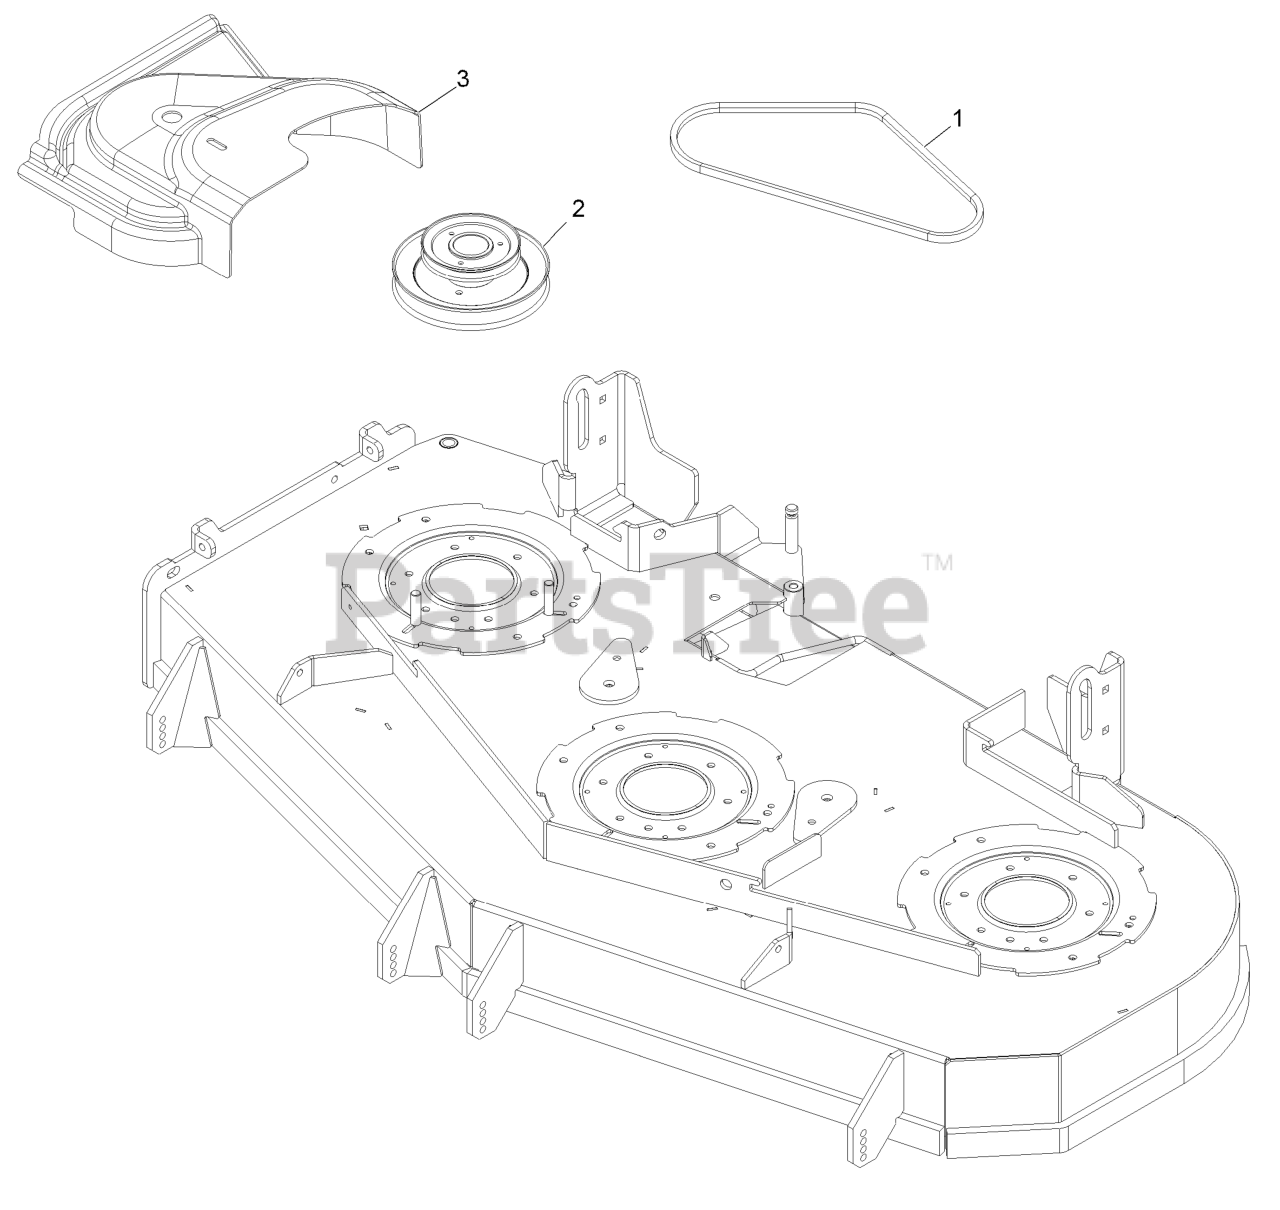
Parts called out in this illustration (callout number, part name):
1	BELT, BLOWER DRIVE 60
2	JACKSHAFT,UV DRIVE 604 SPLINED
3	COVER,BELT UV 60
